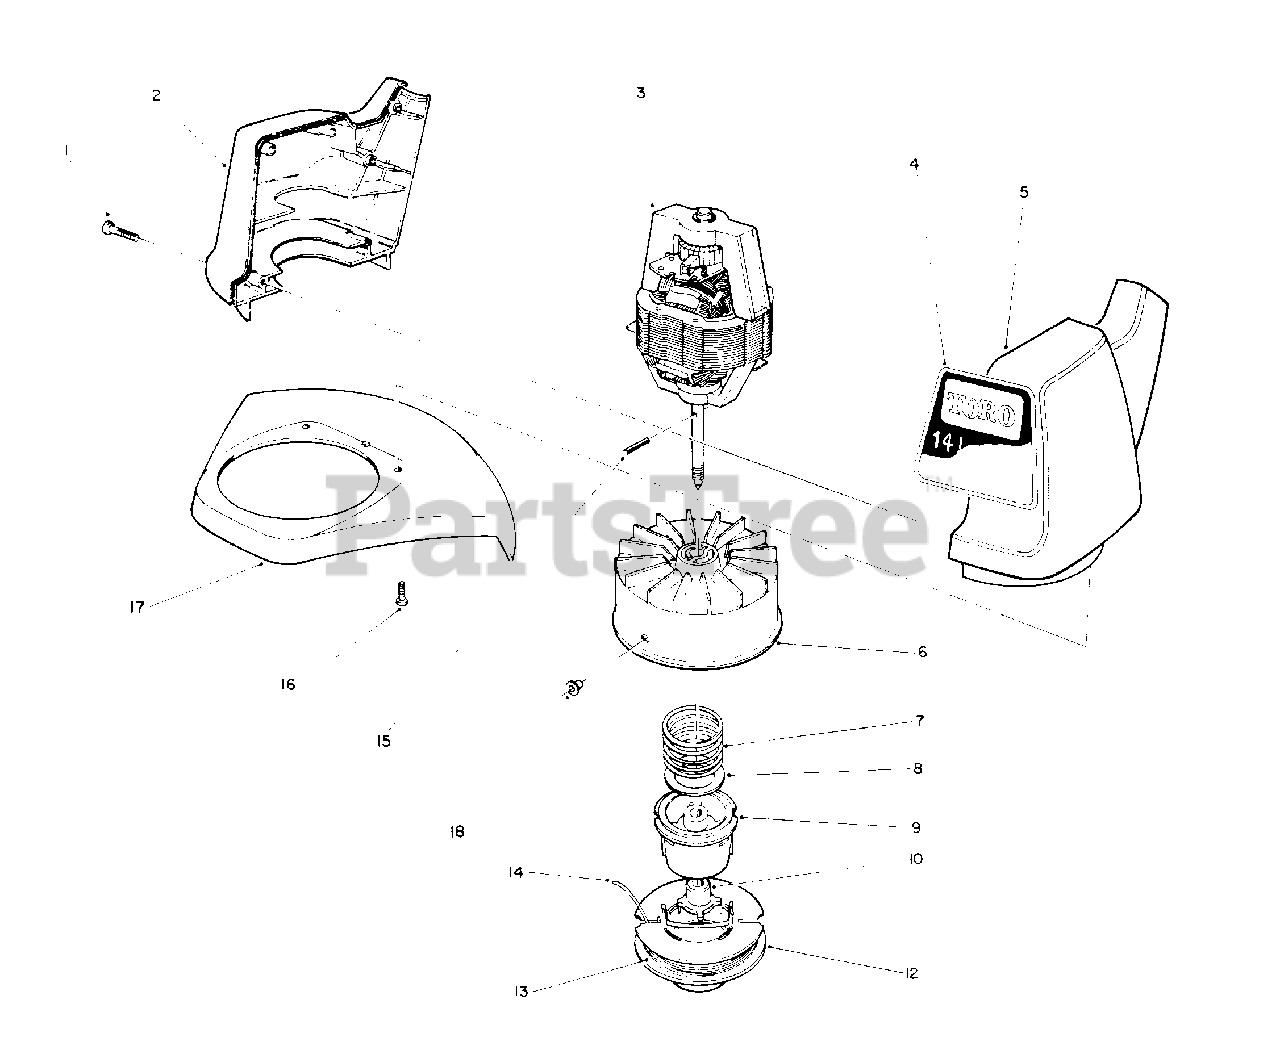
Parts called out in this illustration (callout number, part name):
1	Screw-Thread Forming
2	Housing-Motor R.H.
3	Motor-Electric
4	Decal-14"
5	Housing-Motor L.H.
6	Drum & Eyelet Assembly
7	Spring-Compression
9	Spool-Core
12	Spool-Empty
13	50' Coil-.065" Dia. Cutting Line Prewound on Spool
14	50' Coil-.065" Dia Cutting Line in Coil
15	Pin-Spiral
16	Screw-Thread Forming
17	Shield Assembly
